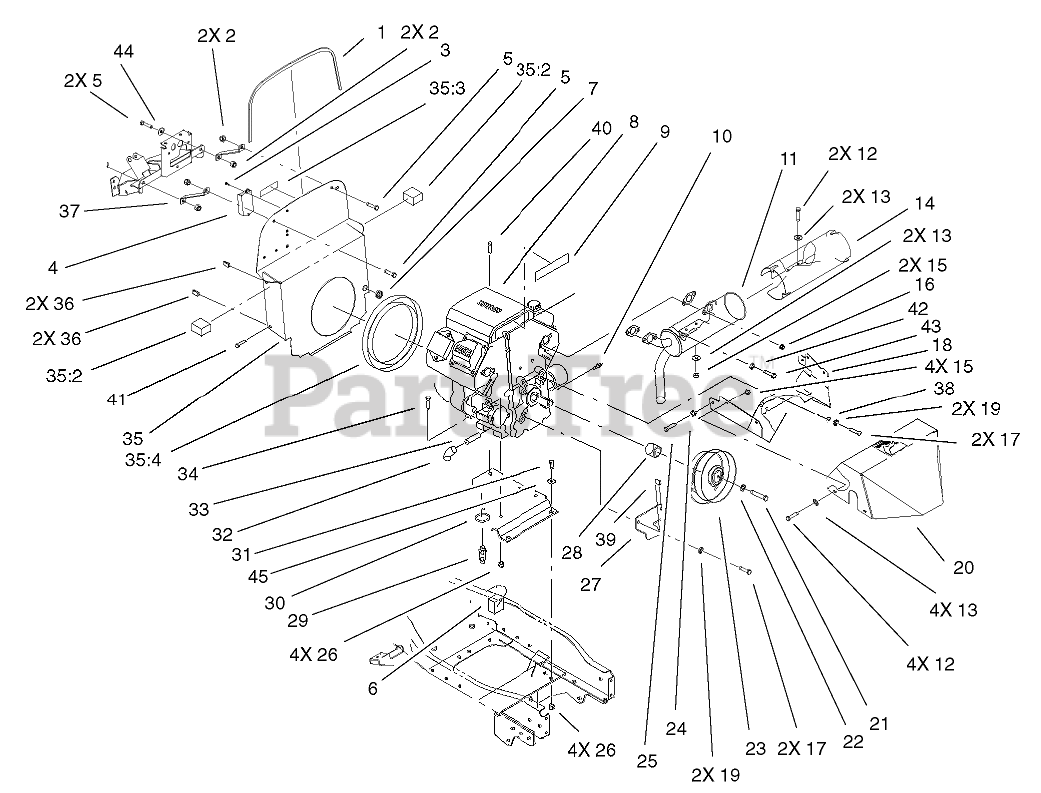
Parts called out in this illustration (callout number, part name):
1	TRIM-LOCK
2	NUT-LOCK, NI
3	SCREW
4	MODULE-LOW VOLTAGE
5	SCREW-HH
6	SEAL-FOAM, SIDE
7	GROMMET
9	DECAL - 22 HP ENGINE
10	SENDER-OIL TEMPERATURE
11	MUFFLER
12	SCREW-HH
13	WASHER-FLAT
14	REFLECTOR - HEAT
15	NUT-LOCK, CONE
16	NUT-HF
17	SCREW-HH
18	SHROUD-MUFFLER
19	WASHER-LOCK
20	SHROUD-MUFFLER
21	SCREW-HH
22	WASHER-FLAT
23	CLUTCH-PTO
24	WASHER-LOCK
25	SCREW-HH
26	NUT-LOCK, NI
27	CLUTCH-STOP
28	SPACER-CLUTCH
29	VALVE-DRAIN, OIL
30	PLATE-ENGINE
31	SCREW-HH
32	ELBOW-90 DEGEE
33	NIPPLE
34	SCREW-HH
35	BULKHEAD / DECAL ASM
35:2	SEAL-FOAM, SIDE
35:3	DECAL-WARNING
35:4	SEAL-FOAM
37	BRACKET-BULKHEAD
38	WASHER-FLAT
39	BUMPER
40	SCREW-TAPTITE
41	SCREW-HH
42	WASHER-LOCK
43	SCREW-HHF
44	WASHER-PLAIN
45	WASHER-FLAT
